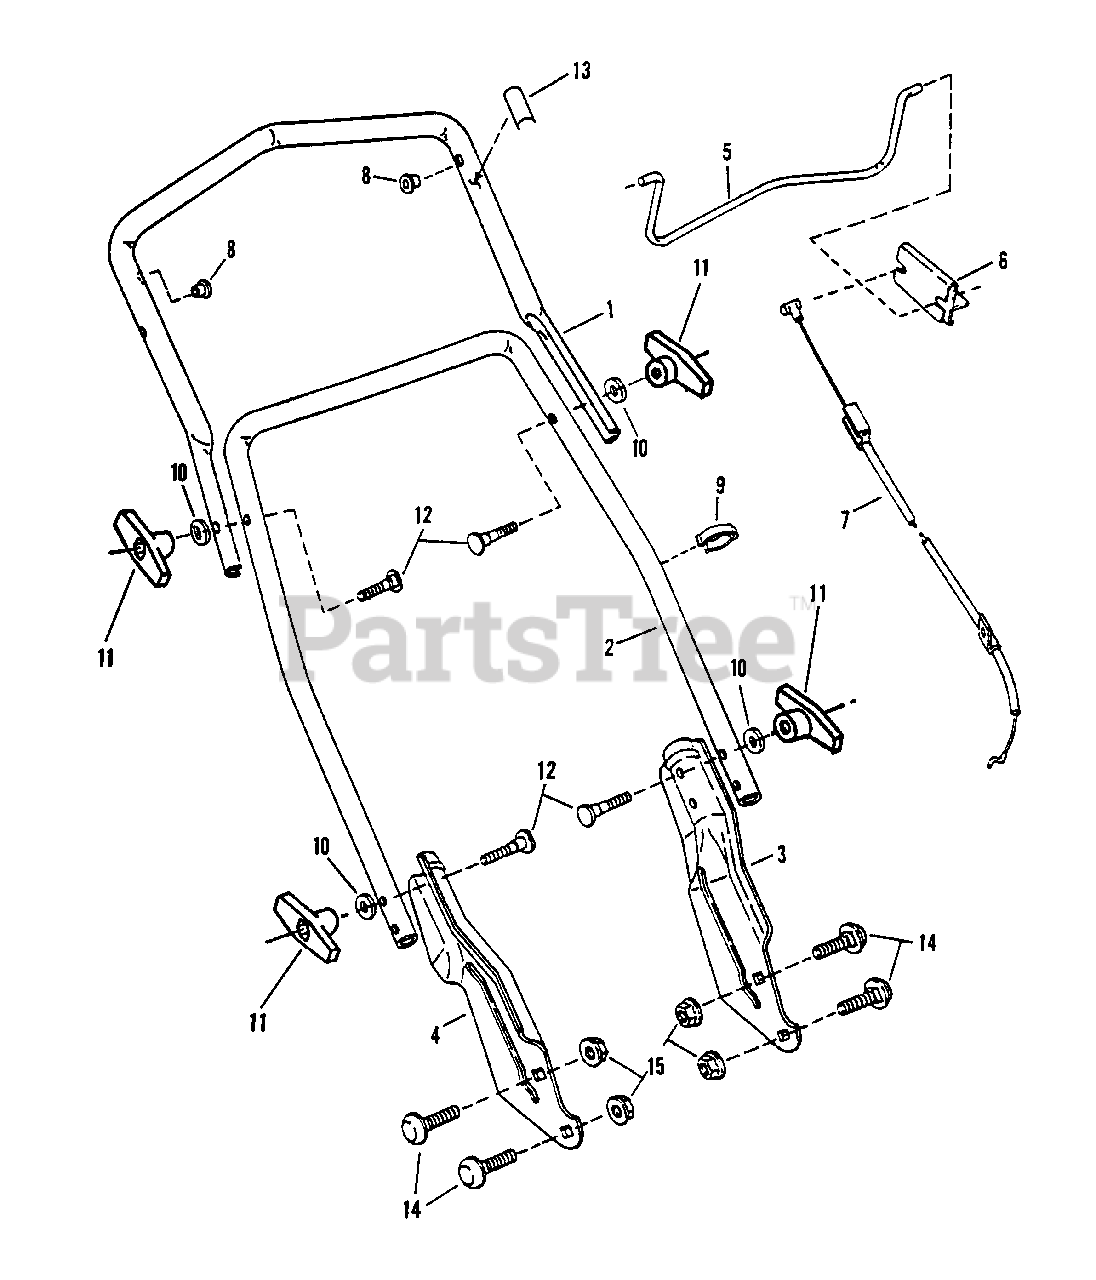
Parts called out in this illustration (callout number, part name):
1	HANDLE, Upper
2	HANDLE, Middle
3	HANDLE, Lower (Left Hand)
4	HANDLE, Lower (Right Hand)
5	CONTROL, Blade
6	CLIP, Blade Control
7	CABLE, Blade Control
8	BUSHING
9	CLIP, Wiring Harness
10	WASHER, 5/16 Internal Tooth Lock
11	KNOB, 5/16-18 T-Style
12	SCREW, 5/16-18 x 2 Curved Head
13	DECAL, Blade Control
14	BOLT, 5/16-18 x 5/8 Short Neck Carriage
15	NUT, 5/18-18 Hex Flange Lock
